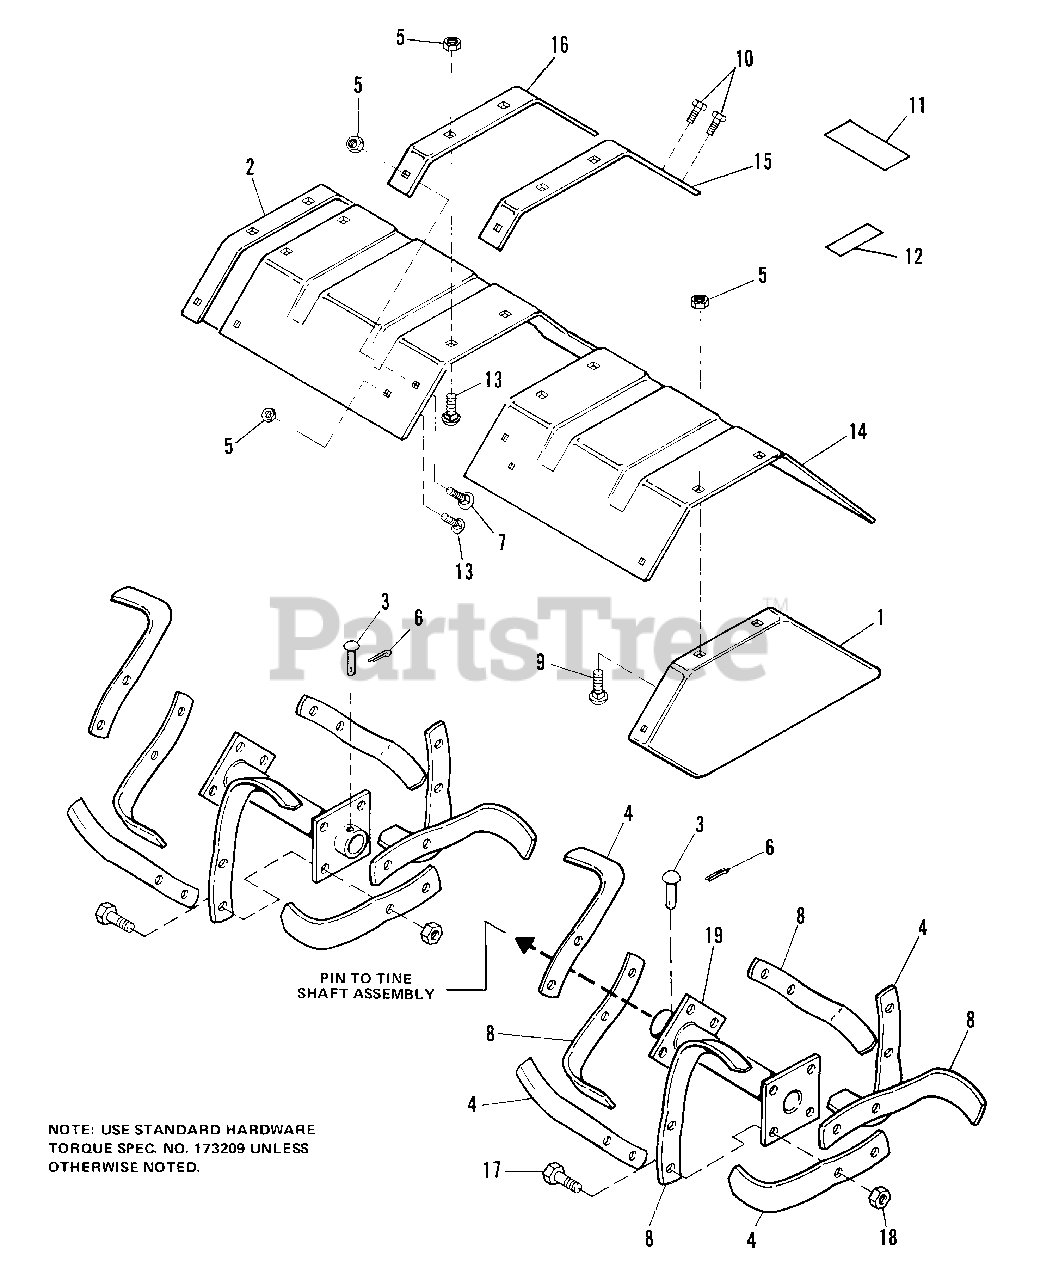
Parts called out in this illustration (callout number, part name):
1	PLATE END, Deflector, L.H.
2	PLATE END, Deflector, R.H.
3	PIN
4	TINE BLADE, L.H.
5	NUT, Hex, Flange, 5/16-18
6	PIN, Cotter, 1/8 x 3/4
7	BOLT, Carriage, 5/16-18 x 3/4
8	TINE BLADE, R.H.
9	BOLT, Carriage, 5/16-18 x 1/2
10	SCREW, Taptite, 5/16-18 x 3/4
11	DECAL, Safety
12	DECAL, Drive Control
13	BOLT, Carriage, 5/16-18 x 5/8
14	DEFLECTOR
15	BAR, Reinf., L.H.
16	BAR, Reinf., R.H.
17	CAPSCREW, Hex, 7/16-20 x 1-1/4
18	LOCKNUT, Hex, 7/16-20
19	HUB & PLATE ASSY, Tine
